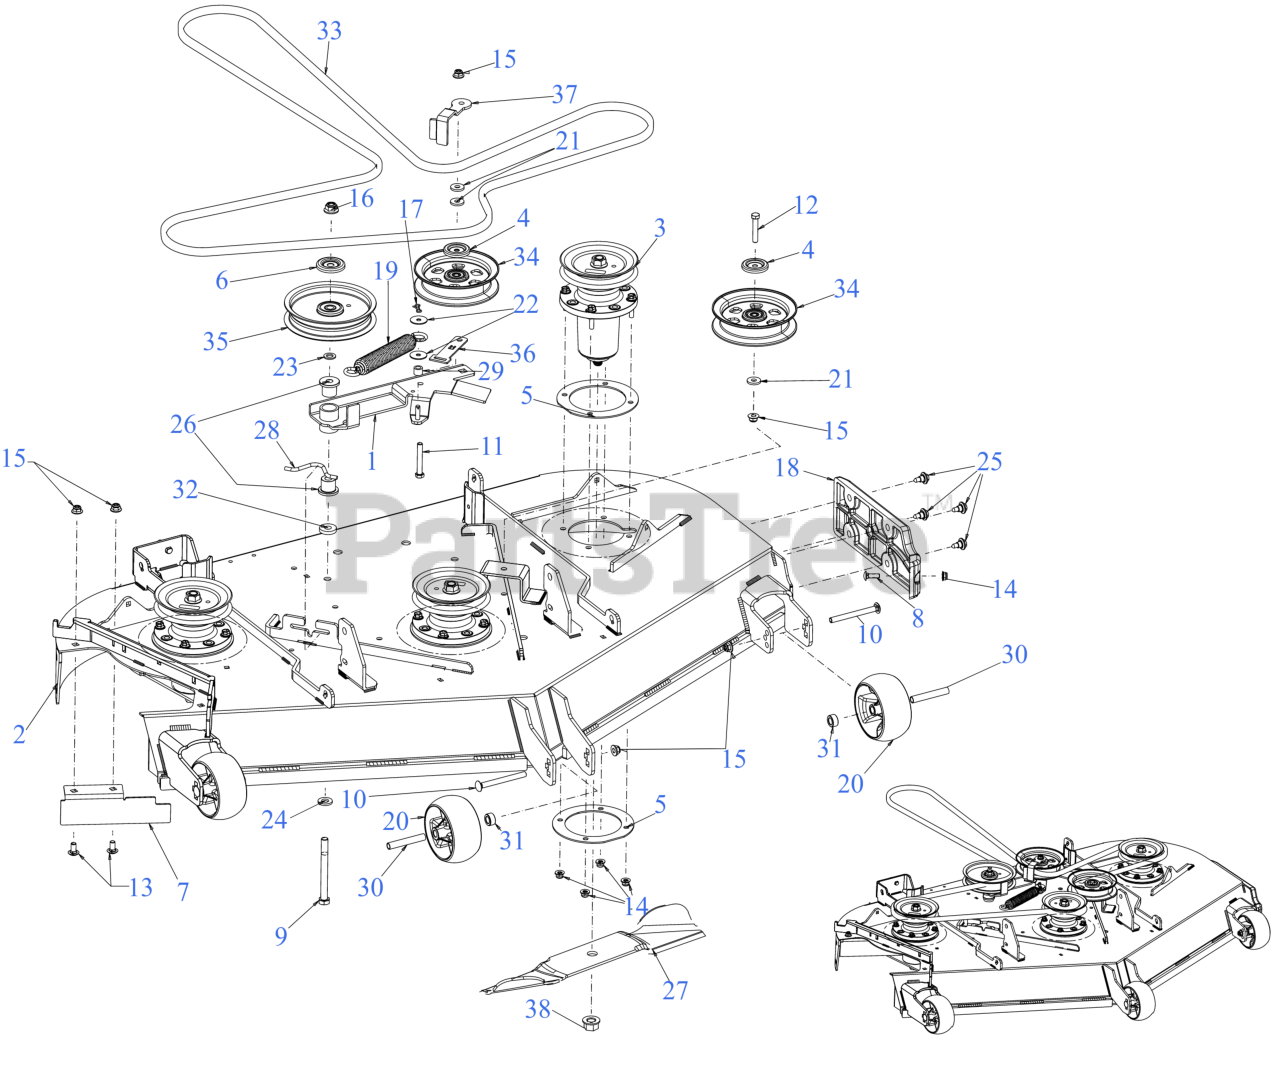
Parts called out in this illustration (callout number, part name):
1	54/60" DECK IDLER ASSEMBLY
2	54" FAB DECK SHELL
3	SPINDLE ASSEMBLY
3	Cub Cadet 54" SPINDLE ASSEMBLY (07416)
4	PULLEY CAP 1.875 DIA
5	SPINDLE PLATE
6	PULLEY CAP (.540 x 2.041 DIA)
7	BAFFLE
8	CARRIAGE BOLT 5/16-18 x 1.00
9	BOLT-HEX 1/2-13X5.0 GR5
10	CARRIAGE BOLT 3/8-16 x 4.00 GR5
11	HEX SCREW-3/8-16X2.5 GR5
12	SCREW 3/8-16 x 2.0 GR5
13	CARRIAGE BOLT 3/8-16 x .75
14	FLANGE LOCK NUT 5/16-18
17	BOW TIE COTTER PIN 1/4-5/16
18	DECK SKID PLATE
19	SPRING 1.25" DIA x 8.5" LONG
20	DECK WHEEL
20	WHEELS-DELUXE 5"
21	FLAT WASHER .385 x 1.00 x .135
22	FLAT WASHER .322 ID x 1.25 x .060
23	FLAT WASHER
24	FLAT WASHER .531X1.060X.134
25	SHOULDER SCREW .43X.29X5/16-18 TT
26	FLANGE BEARING
28	DECK SPRING HOOK
30	SPACER .38X.49X3.05LG
31	SPACER-.505 1D
32	SPACER PLATE
33	V-BELT B SEC x 148.25
33	Cub Cadet 54" DECK DRIVE BELT
34	5" FLAT IDLER PULLEY
35	IDLER PULLEY 6.0"
36	BELT KEEPER
37	54/60" IDLER KEEPER
38	FLANGE NUT - 5/8-18 GDE 8
